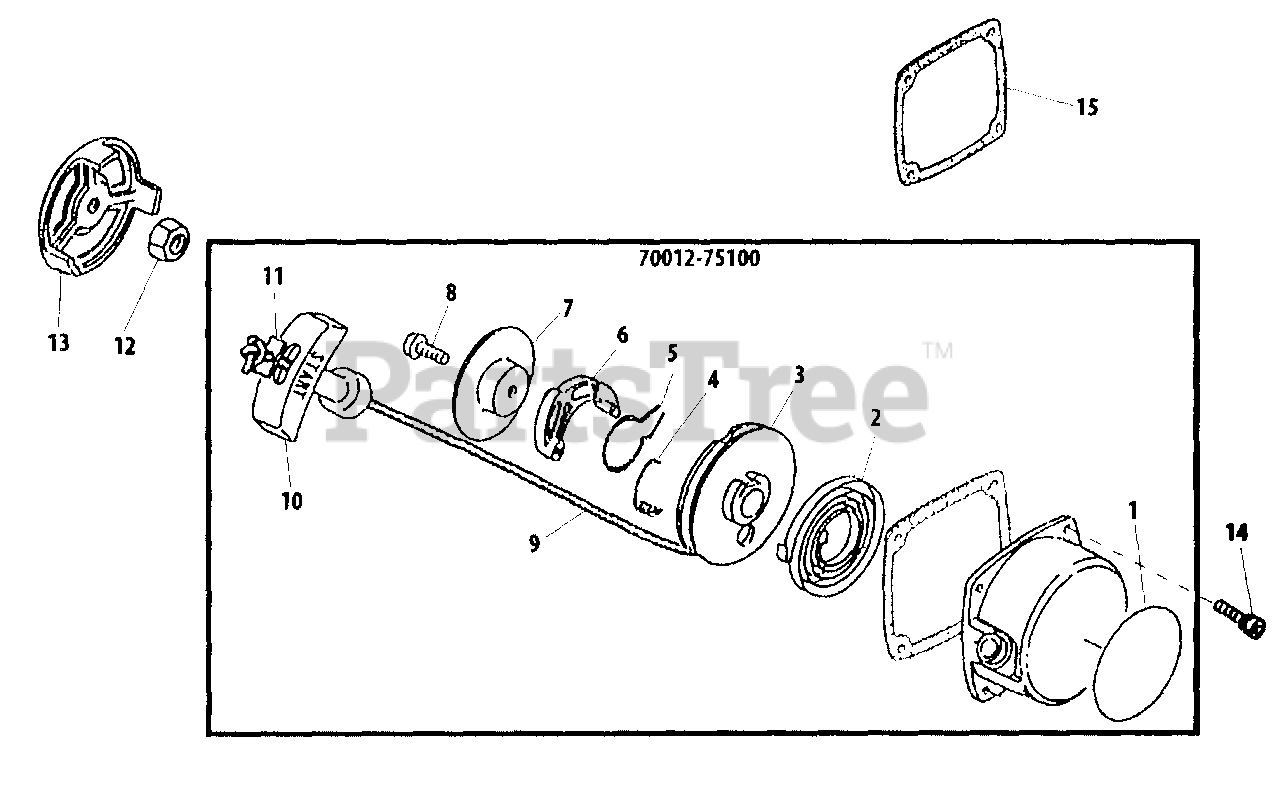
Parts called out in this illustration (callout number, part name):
1	LABEL, TRADE
2	SPRING, RECOIL
3	REEL, ROPE
4	SPRING, RETURN
5	SPRING, FRICTION
6	RATCHET
7	PLATE, FRICTION
8	SCREW
9	ROPE
10	GRIP, STARTER
11	RETAINER, ROPE
12	NUT M8×H5
13	PULLEY, STARTER
14	BOLT M4×16
15	GASKET
70012-75100	STARTER ASSY, RECOIL
